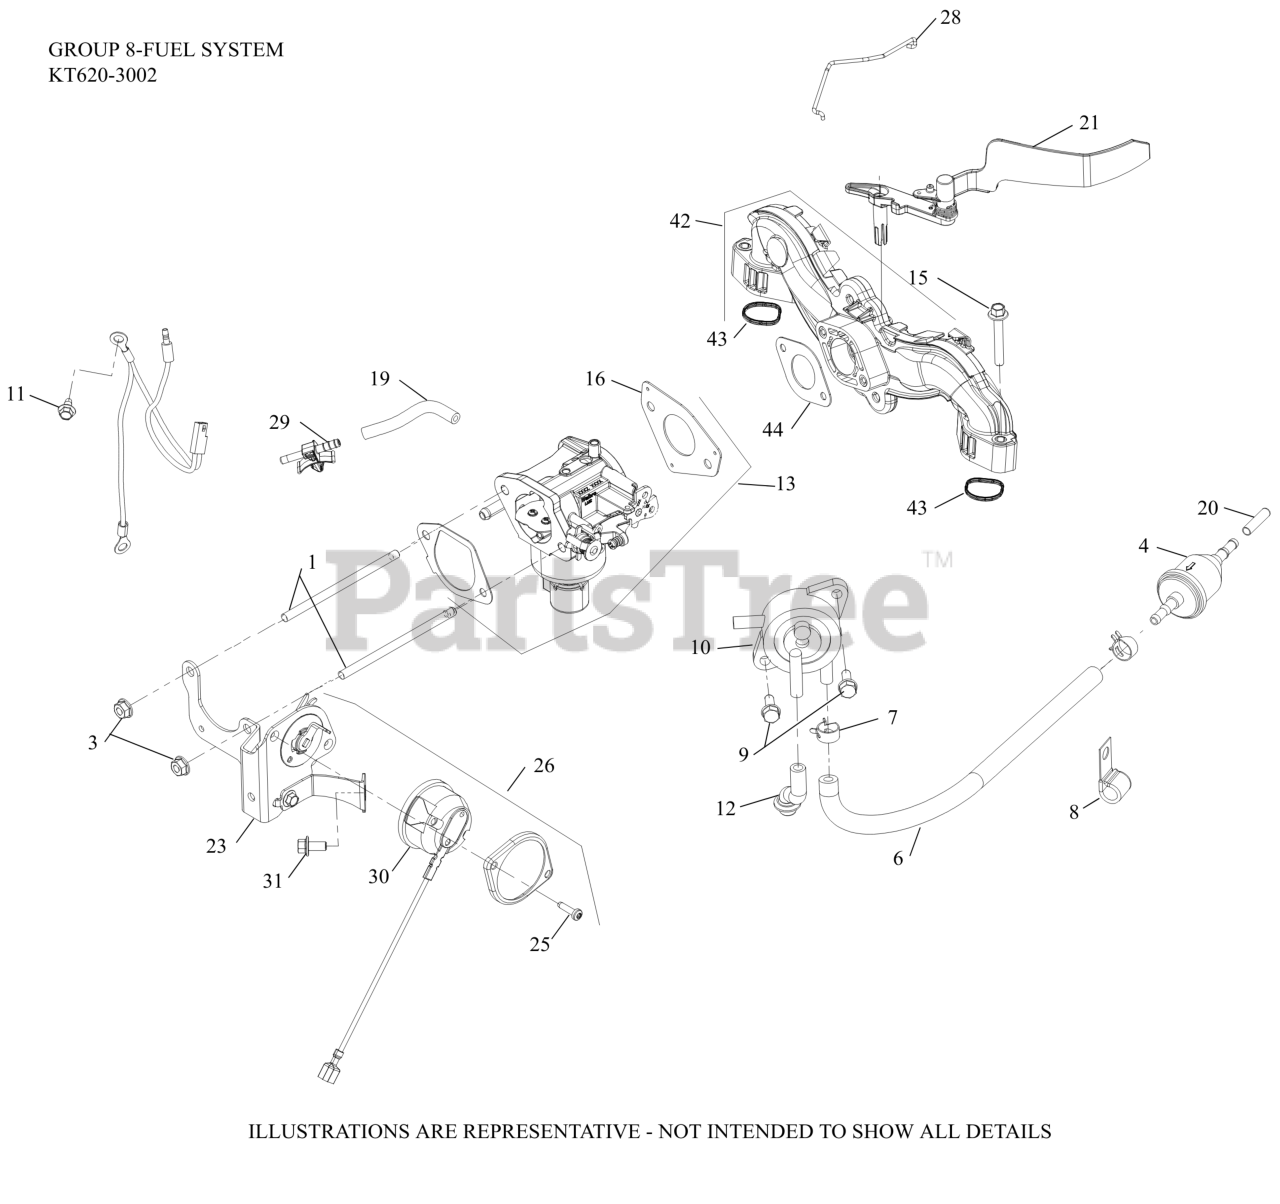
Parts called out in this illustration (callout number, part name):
3	NUT, FLG M6X1.0
4	FILTER,FUEL 51 MICRON (FUEL PUMP)
6	HOSE,LW PERM.FUEL 24.00"-USE 25 111 81-S
7	SPRING CLAMP, HOSE
8	CLIP, CABLE (KM)
9	SCREW, TAP M6X1.7X18
10	PUMP, FUEL (PULSE)-(#2539326S)
11	SCREW, THREAD FORMING
12	HOSE, PULSE PUMP(STEEL COVERS)
13	KIT,CARB(WALBRO)
15	SCREW, FLG M6X1.0X40
16	GASKET, CARBURETOR
19	HOSE EVAPORATIVE (WALBRO)
20	CAP, MASKING
21	DEFLECTOR ASSEMBLY, AIR VANE
23	BRACKET ASSY, AUTO-CHOKE (MECH)
25	SCREW, PAN HEAD THREAD FORMING (M4)
26	THERMOSTAT ASSY (CDI) - USE 32 755 27-S
26	THERMOSTAT ASSY(MDI IGN)-USE 32 755 27-S
28	LINKAGE, CHOKE UPLOADER
29	CONNECTOR, EVAPORATIVE
30	KIT, THERMOSTAT, ELECTRIC CHOKE
31	SCREW, FLG M6X1.0X12
42	INTAKE MANIFOLD W/GASKETS
43	O-RING, INTAKE PORT
44	GASKET, CARBURETOR (PIM, CV)
NI	KIT,REPAIR OVERHAUL(WALBRO)
NI	KIT,BOWL O-RING(WALBRO)
NI	KIT, HI ALTITUDE (5000 FT) 19MM
NI	KIT,SOLENOID REPAIR(WALBRO)
NI	KIT,REPAIR FLOAT(WALBRO)
